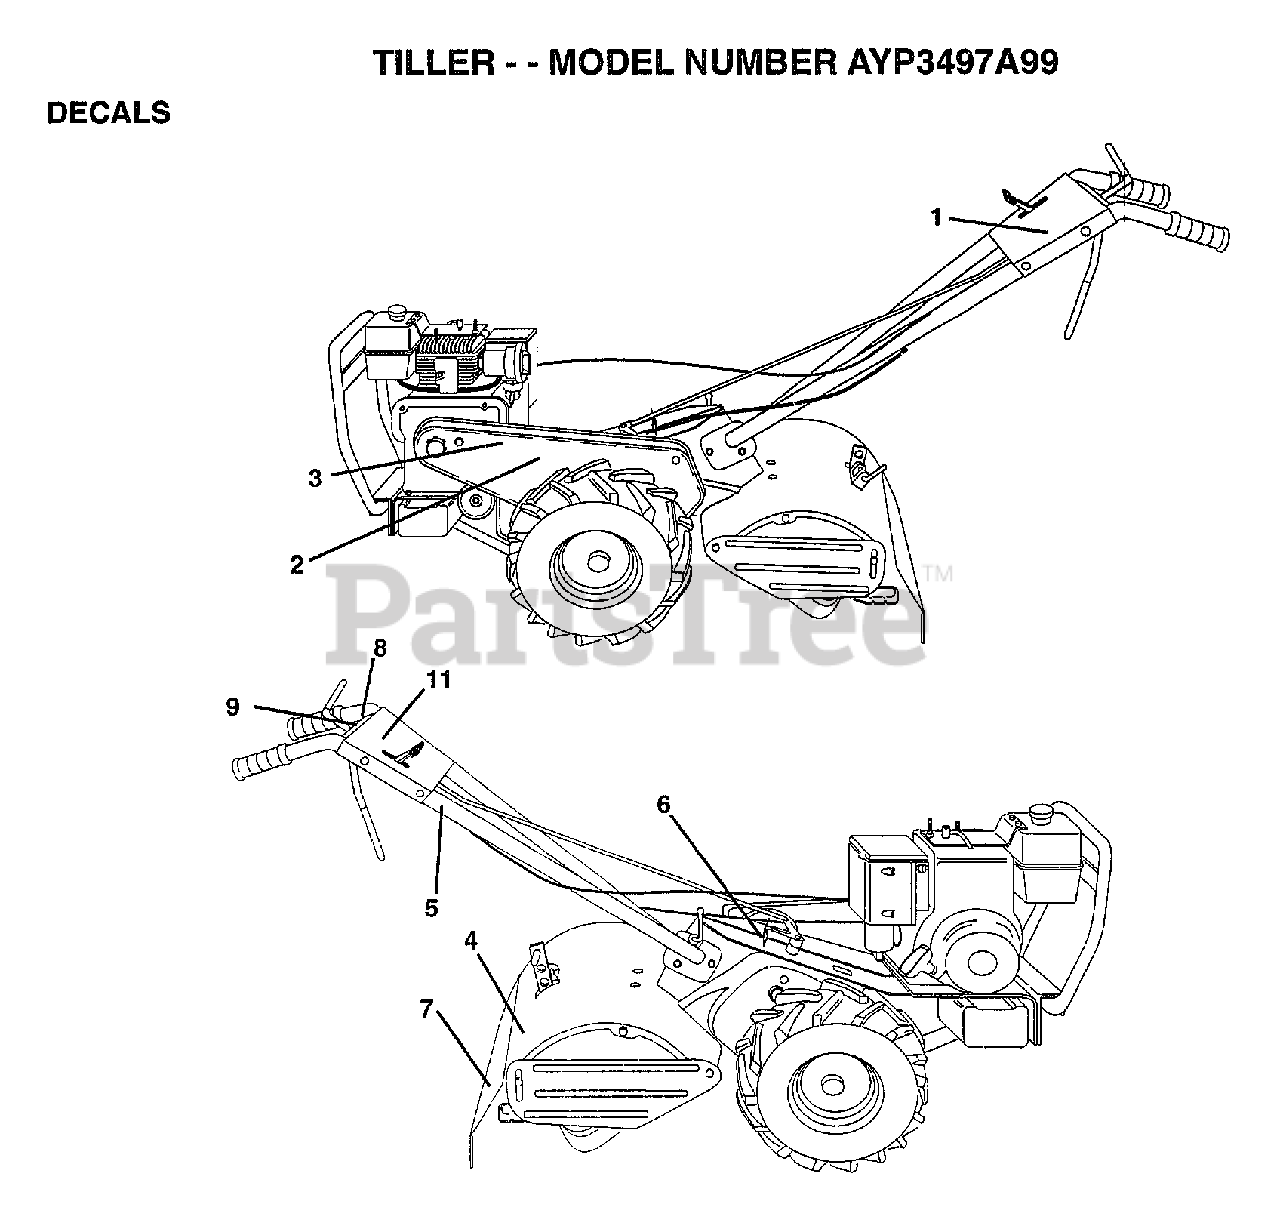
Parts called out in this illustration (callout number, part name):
1	DECAL, LOGO
3	DECAL.GUARD.BLT.W
5	DECAL TI
6	DECAL.SHIFT.IND.
7	DECAL TI
9	DECAL.TINE.SHIELD
11	DECAL.PANEL 8 HP
